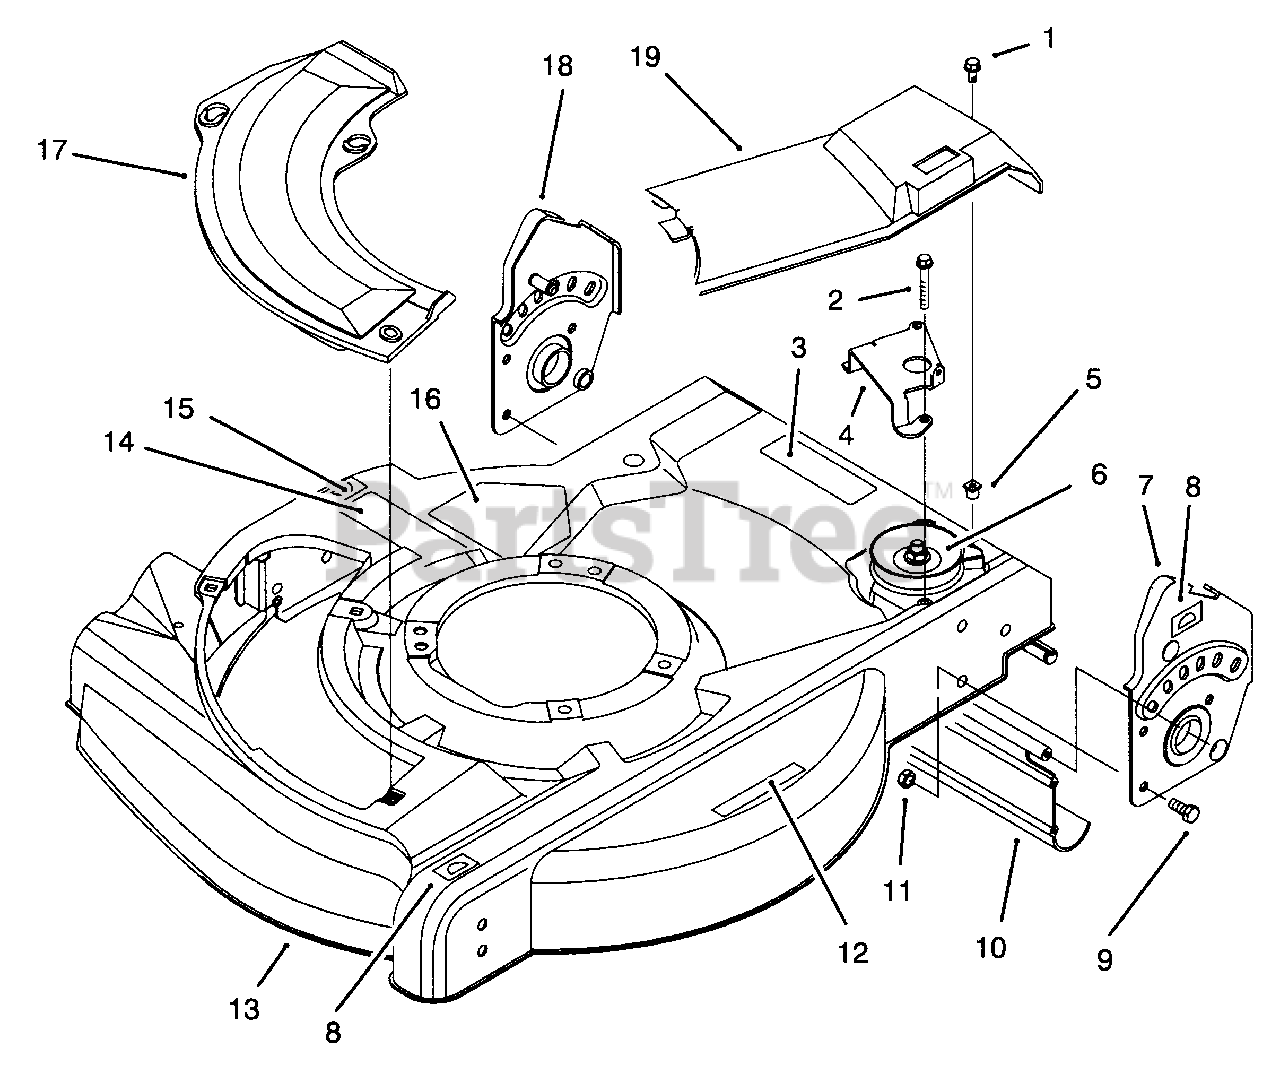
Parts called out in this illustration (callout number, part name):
1	Screw-Phillips Hd. (Model No. 10312 Only)
2	Screw-Hex Hd. (Model No. 10312 Only)
3	Decal-Warning
4	Guide-Transmission (Model No. 10312 Only)
5	Grommet (Model No. 10312 Only)
6	Gear Case Assembly (Model No. 10312 Only)
7	Bracket-Handle L.H. (Model No. 10312 Only)
8	Decal-H.O.C.
9	Screw-Hex Hd. Cap
10	Shield-Trailing
11	Nut-Lock
12	Decal-Warning
13	Housing (Model No. 10312 Only)
14	Decal-Discharge
15	Decal-H.O.C.
16	Decal-Danger
17	Plate-Cover
18	Bracket-Handle R.H. (Model No. 10312 Only)
19	Cover-Drive (Model No. 10312 Only)
